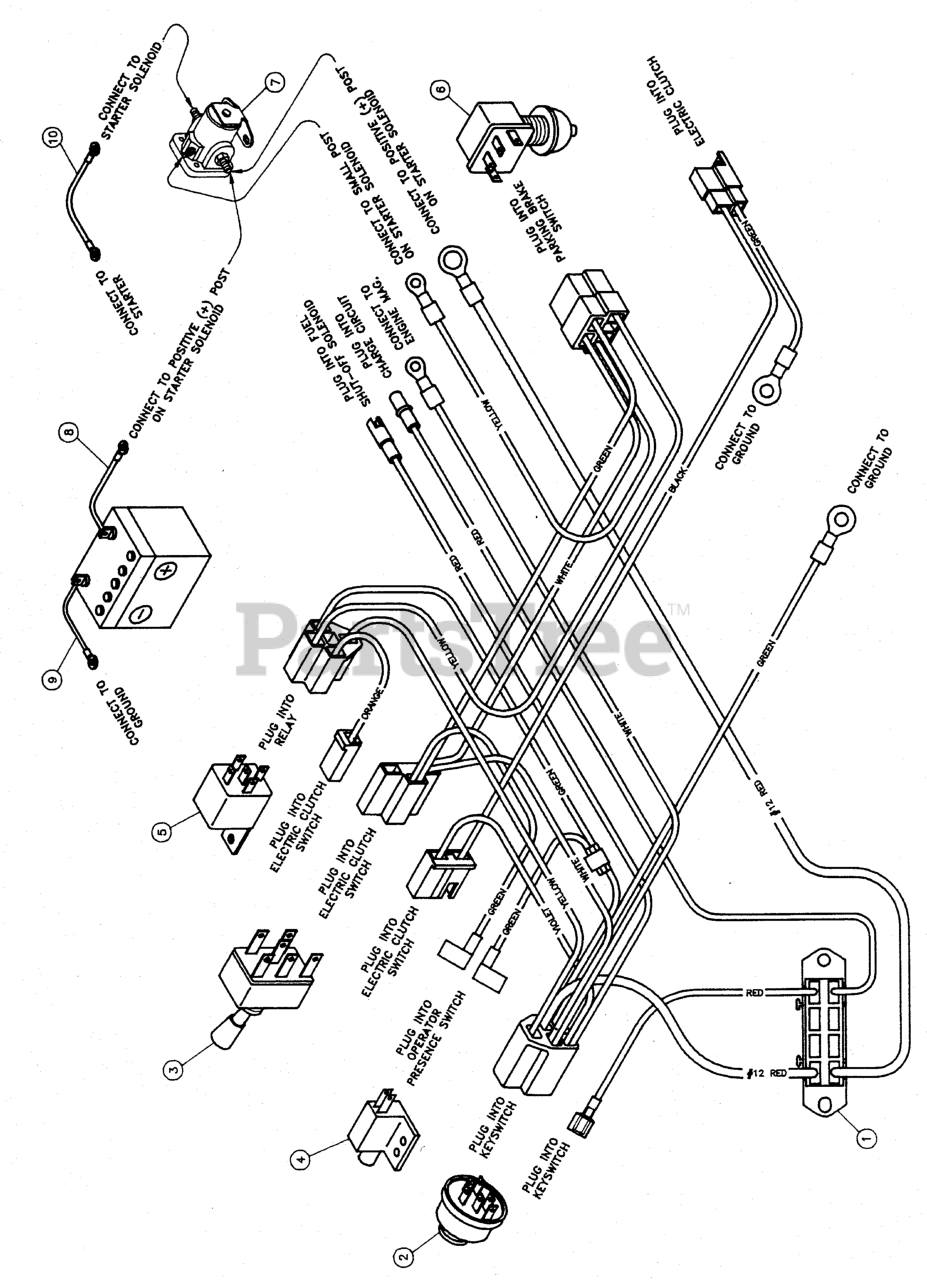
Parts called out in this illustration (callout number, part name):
1	DD Briggs Wiring Harness
2	SWITCH, IGNITION, 6 POST
3	SWITCH, Electric Clutch
4	SWITCH, PLUNGER, N.C.
5	Relay
6	Parking Brake Switch
7	SOLENOID, Starter
8	POSITIVE (+) BATTERY CABLE, 30"
9	BATTERY CABLE, NEG, 22, 1/4-5/16
10	Starter Cable
